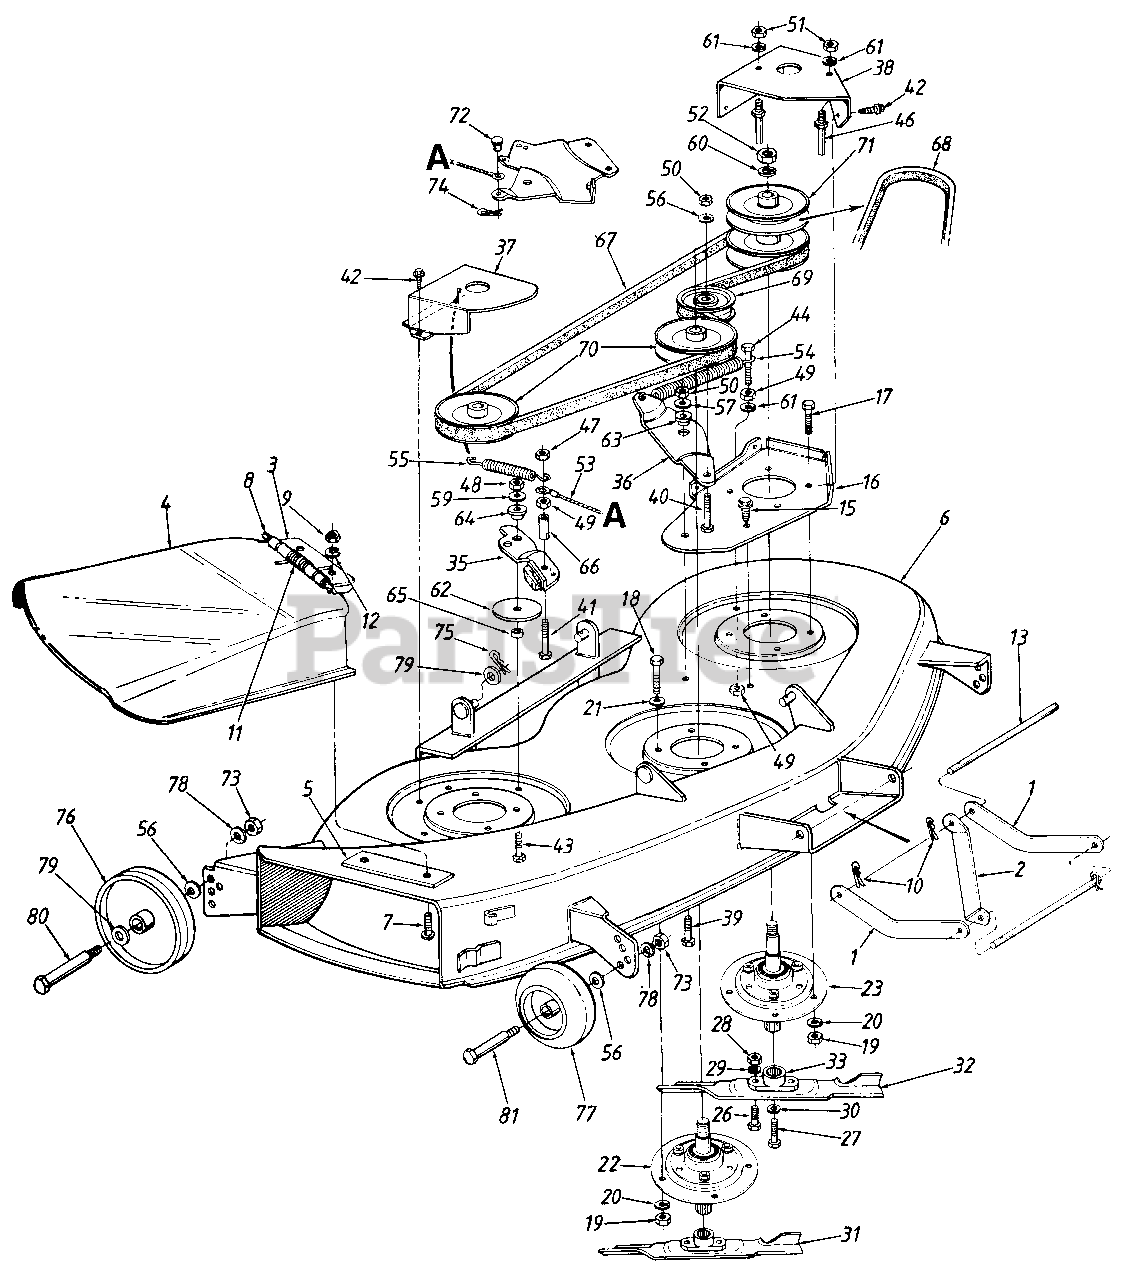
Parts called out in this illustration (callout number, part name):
4	Deck Chute
5	Chute Mtg. Plate
6	46" Deck Ass'y.
7	Truss Mach. Scr. 1/4-20 x .75"
8	Hinge Pin
9	Hex Jam Nut 1/4-20 Thd.
10	Int. Coter Pin
11	Torsion Spring
12	Bell-Wash. 1/4" I.D.
13	Deck Connecting Rod
15	Hex TT-Tap Scr. 5/16-18 x.62"
18	Hex Bolt 5/16-24 x .75" Lg.
19	Hex Nut 5/16-24 Thd.
20	L-Wash. 5/16" I.D.*
21	Bell-Wash. 5/16" I.D.
22	Spindle Ass'y.
23	Spindle Ass'y.
26	Hex Bolt 5/16-24 x 1.25" Lg.(Grade 5)
27	Hex Cl-Bolt 3/8-24 x .88" Lg.
28	Hex Nut 5/16-24 Thd.
29	L-Wash. 5/16" I.D.*
30	L-Wash. 3/8" I.D.H.D.
31	High Lift Blade 14.88" Lg.
32	High Lift Blade 16.28"
33	Blade Adapter
35	Deck Brake Brkt. Ass'y.
36	Idler Bracket
40	Hex Bolt 3/8-24 x 1.5" Lg.
41	Hex Bolt 1/4-28 x 1.75" Lg.
42	Hex Wash. Hd. Tap-Scr. 1/4-20 x .5" Lg.
43	Hex Bolt 5/16-24 x 1.25" Lg.(Grade 5)
44	Hex Bolt 1/4-28 x 1.5" Lg.
46	Belt Guard Pin 1/4" Dia.
47	Hex Cent. L-Nut 1/4-28 Thd.
48	Hex Nut 5/16-24 Thd.
49	Hex Nut 1/4-28 Thd.
50	Hex Nut 3/8-24 Thd.
51	Hex Nut 1/4-20 Thd.
52	Hex Jam Nut 5/8-18 Thd.
53	Brake Cable Ass'y.
54	Extension Spring 6.12" Lg.
55	Extension Spring 3.97" Lg.
56	Bell-Wash. .38" I.D. x .88" O.D.
57	Bell-Wash. .39" I.D. x 1.13" O.D.
59	Bell-Wash. .345" I.D. x .88" O.D.
60	Bell-Wash. 518" I.D. x 1.25" O.D.
61	L-Wash. 1/4" I.D.
62	Fl-Wash. 5/16" I.D. x 3" O.D.
63	Shld. Spacer .625" I.D.
64	Shld. Spacer
65	Spacer.34" I.D.
66	Spacer.326" I.D.
67	V-Belt
68	V-Belt
69	Fl-ldler w/Flanges 3.5" O.D.
70	Pulley 5.0" Dia.
71	Pulley 5.0" Dia.
72	Clevis Pin 1/4" Dia. x .53" Lg.
73	Hex Nut 3/8-16 Thd.
74	Intern. Coter Pin 5/16" Dia.
75	Intern. Coter Pin 3/8 Dia.
76	Deck Wheel 5" Dia.
77	Deck Wheel w/lnsert 5" Dia.
78	L-Wash. 3/8" I.D.
79	Fl-Wash. .531" I.D.
80	Shoulder Bolt .498" Dia. x 1.64" Lg.
81	Shoulder Bolt
